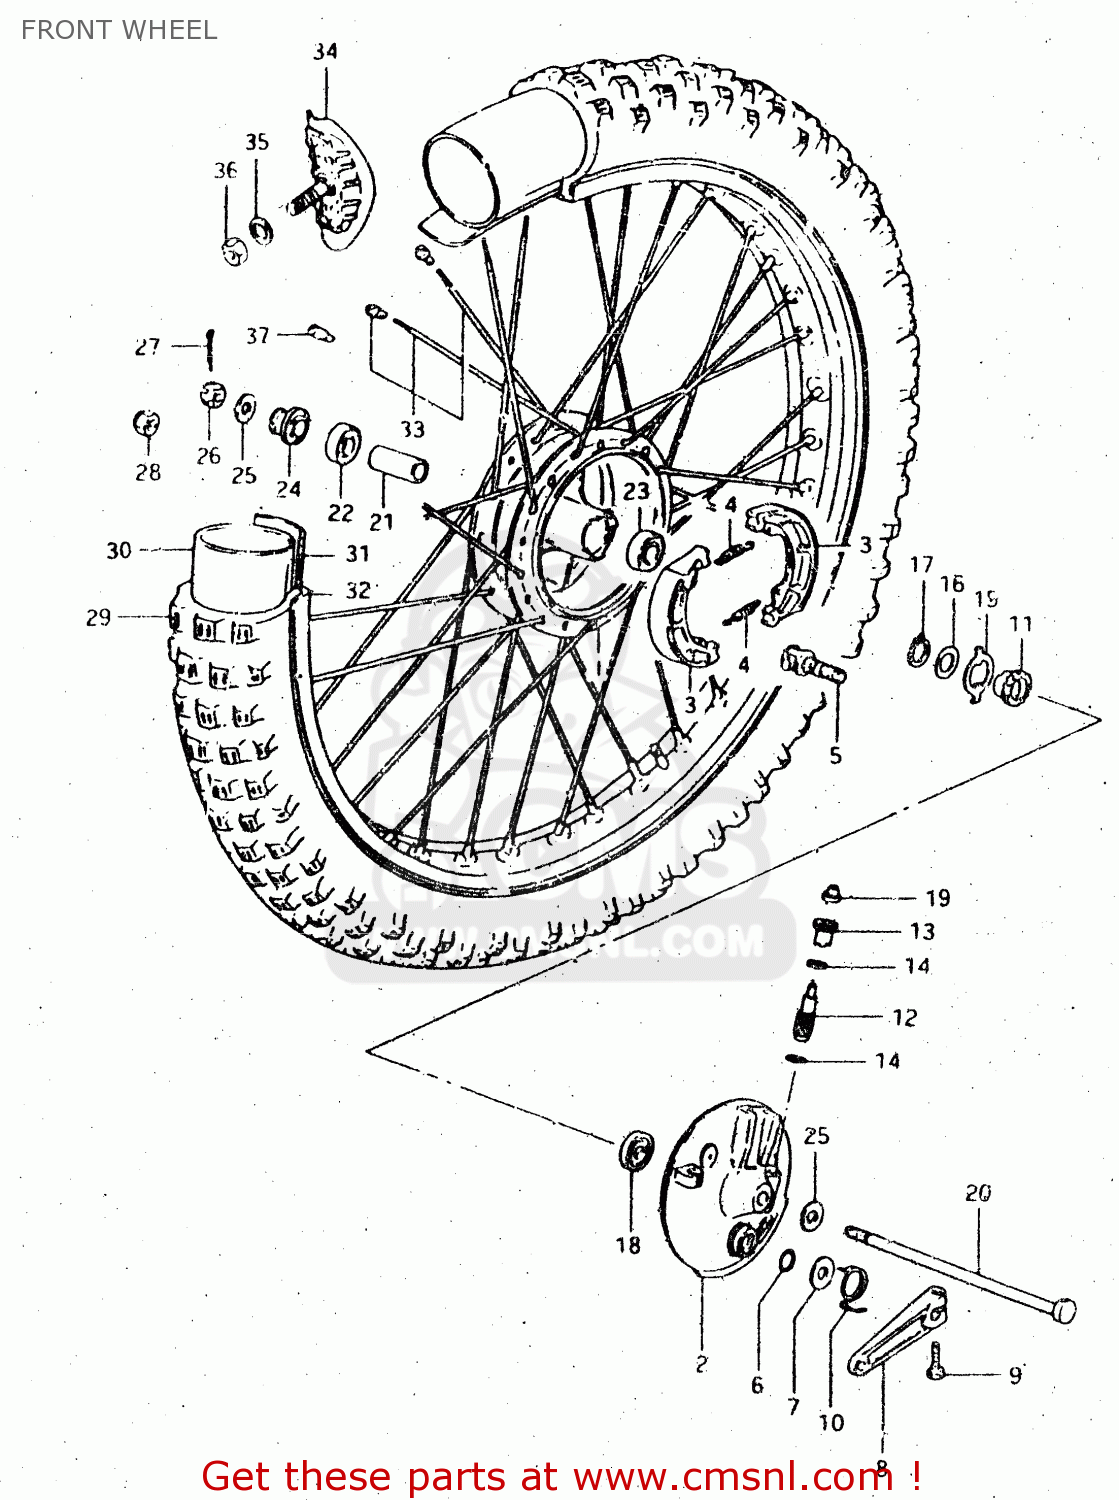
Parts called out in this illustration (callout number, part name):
1	DRUM,FRONT HUB
2	PANEL,FRONT BRAKE
3	SHOE,BRAKE
4	SPRING
5	CAM,FRONT BRAKE
6	O-RING,BOSS
7	WASHER (15X24X1.6)
8	LEVER,FRONT BRAKE CAM
9	BOLT
10	SPRING
11	GEAR,SPEEDOMETER
12	PINION,SPEEDOMETER
13	BUSHING,SPEEDOMETER PINION
14	WASHER (5.1X9X0.4)
15	DRIVER,SPEEDOMETER GEAR
16	WASHER(22.5X27X1)
17	CIRCLIP
18	SEAL,OIL(26X38X4)
19	SEAL,OIL(6X10X3)
20	AXLE,REAR
21	SPACER (12.6X19X52)
22	BEARING, RH
23	BEARING
24	SPACER,FRONT AXLE,RIGHT
25	WASHER
26	NUT, REAR AXLE
27	COTTER PIN
28	NUT 12MM
29	TIRE 3.00-21
30	TUBE
31	PROTECTOR,WHEEL,INNER
32	RIM,FRONT WHEEL (1.60X21)(
33	SPOKE SET,FRONT
34	STOPPER,BEAD
35	WASHER
36	NUT
37	BALANCER,WHEEL (50G)
